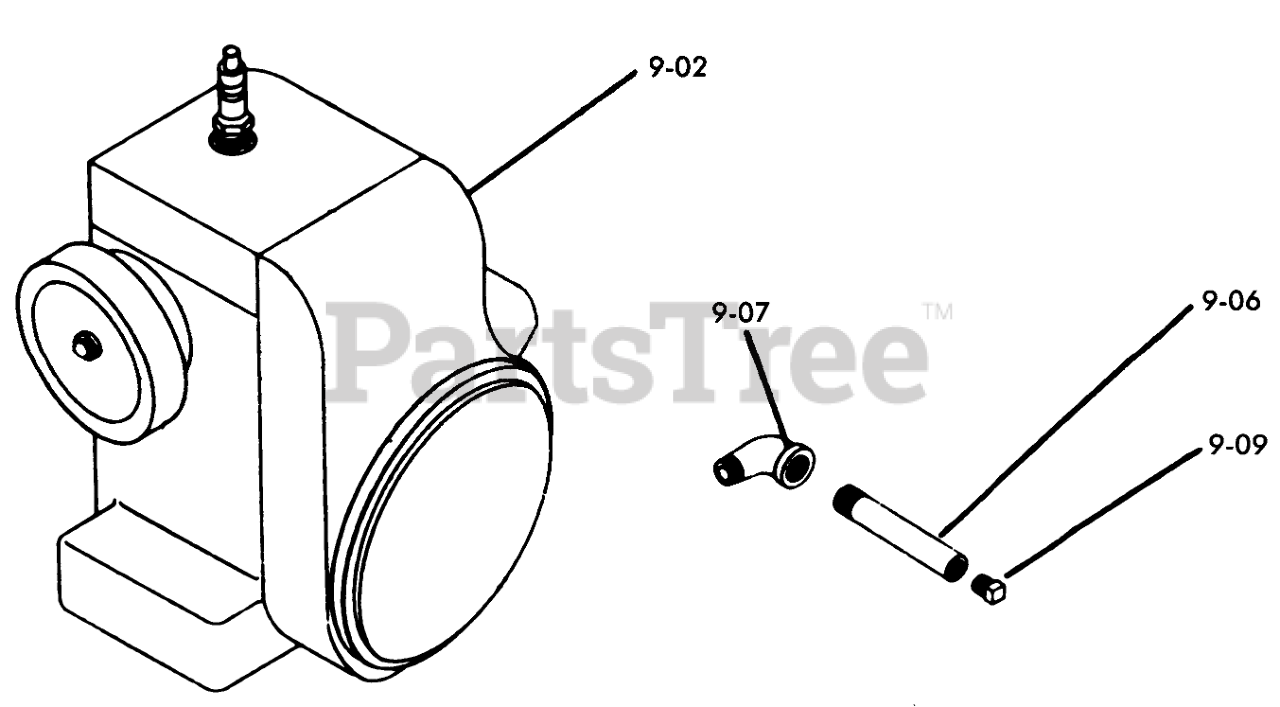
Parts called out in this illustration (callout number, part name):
9-02	Engine-12HP Kohler
9-02	Engine-1OHP Kohler
9-02	Engine-16HP Kohler
9-02	Engine-8HP Kohler
9-02	Engine-7HP Kohler
9-02	PLATE COIL & SOL MTG
9-02	Engine Base
9-02	BOLT
9-02	NUT
9-02	LOCKWASHER
9-06	Nipple 3/8 x 5
9-07	ELBOW-STREET
9-09	Cap
